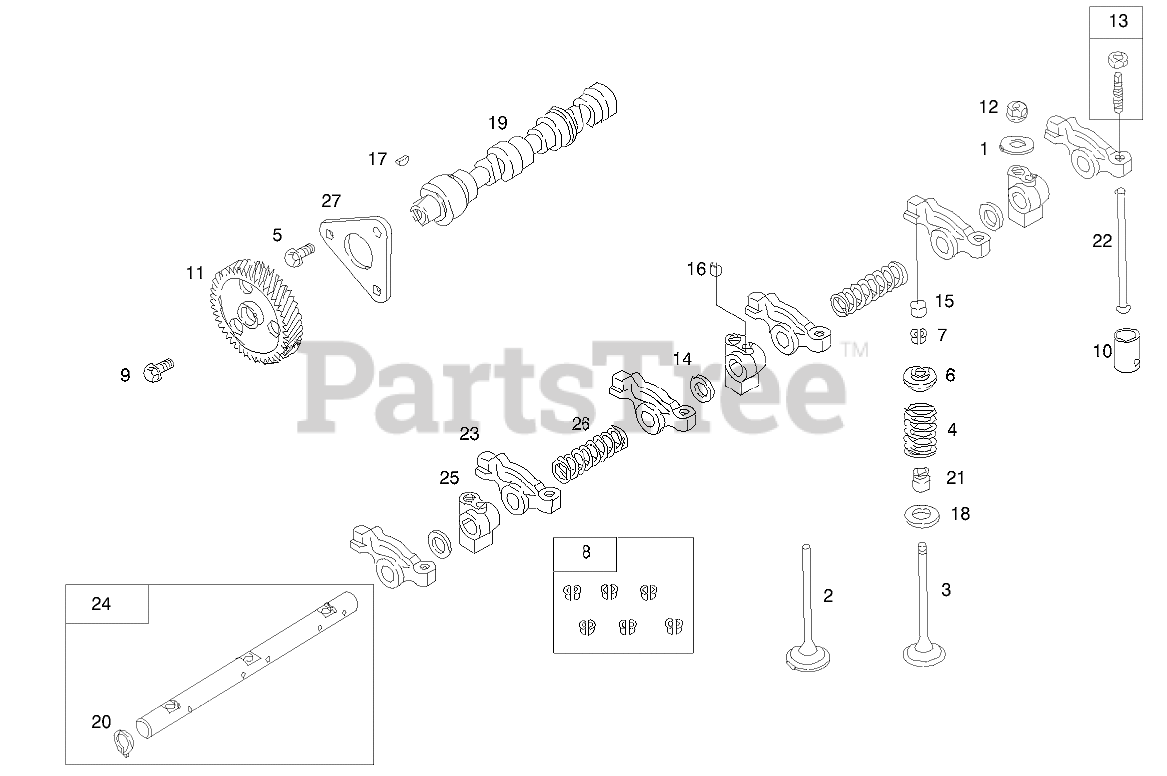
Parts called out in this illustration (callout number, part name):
1	WASHER-FLAT
2	VALVE-EXHAUST
3	VALVE-INTAKE
4	SPRING-VALVE
4	NIPPLE ASM
5	SCREW-HEX
5	VALVE ASM
6	RETAINER-VALVE
7	KEEPER-VALVE (SET)
8	KEEPER-VALVE (SET OF 6)
9	SCREW-METRIC
9	GASKET-SET
10	TAPPET-VALVE
11	GEAR-CAM
12	NUT-HEX, METRIC
13	ADJUSTER-ARM, ROCKER
14	WASHER-SPACER
14	VALVE OVERHAUL KIT
15	CAP-VALVE
15	SHAFT-GEAR
16	SCREW-METRIC
17	KEY-TIMING
18	SEAT-SPRING, VALVE
19	SHAFT-CAM
20	RETAINER
21	SEAL-VALVE
22	ROD-PUSH
23	ARM-ROCKER
24	SHAFT-ARM, ROCKER
25	SUPPORT-ARM, ROCKER
26	SPRING-SHAFT, ROCKER
27	RETAINER-CAMSHAFT
